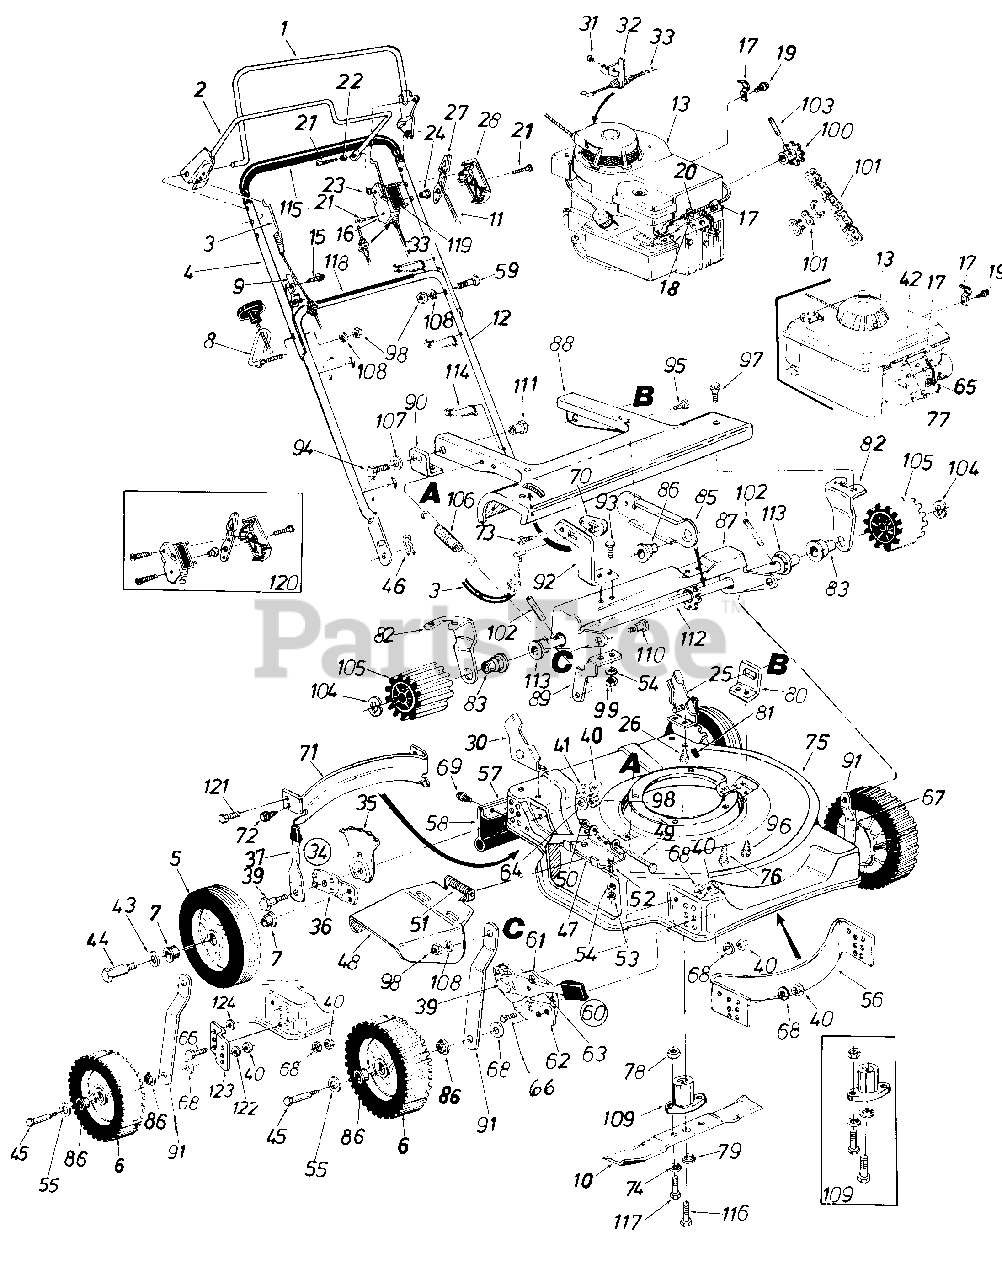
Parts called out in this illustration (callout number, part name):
1	Control Handle Ass'y.
2	Control Handle
3	Control Cable w/Spring- 47" Lg. (Green)
4	Upper Handle
5	Rear Wheel Ass'y. Comp.
6	Front Wheel Ass'y. Comp.
7	Flange Brg. 1/2" I.D.
8	Rope Guide Bolt
9	Cable Mtg. Brkt.
10	22" Blade
11	Throttle Wire-58" Lg. (Green)
12	Lower Handle
13	Engine
15	Hex AB-Tap Scr. 5/16-18 x 314
16	Clutch Panel Half
17	Casing Clamp
18	Hex AB-Tap Scr. #8 x .50 Lg.
19	Hex B-Tap Scr. #10 x .38 Lg.
20	Casing Clamp
21	Truss Hd. B-Tap Scr. #12 x 1.5" Lg.
22	Spacer .23 I.D. x .30 O.D.
23	Spr. Wash. .206 I.D. x .448 O.D.
24	Control Disc Pin
25	Handle Mtg. Brkt. Ass'y.
26	Hex B-Tap Scr. 5/16-18 x .50"
27	Throttle Control Lever
28	Control Panel Half
30	Handle Mtg. Brkt. Ass'y.
31	Pop Rivet .156 Dia. x .316 Lg.
32	Cable Bracket
33	Control Cable-43" Lg. (Yellow)
34	Rear Height Adjustment Ass'y.-R.H.
35	Index Plate
36	Wheel Pivot Bar
37	Spring Lever w/Knob
39	Shld. Bolt .500" Dia. x .430" Lg.
40	Hex Nut 3/8-16 Thd.
41	Bell-Wash. .39 I.D. x 1.38 O.D. x .062
42	Casing Clamp
43	Bell-Wash. .40 I.D. x .88 O.D. x .06
44	Rear Axle Bolt
45	Front Axle Bolt
46	Int. Cot. Pin 5/16 Dia.
47	Adapter Plate
48	Chute Deflector Ass'y.
49	Pivot Pin
50	Cap Speed Nut 1/4 Rod
51	Torsion Spring
52	Hex Bolt 1/4-20 x .50 Lg.
53	Hex Nut 1/4-20 Thd.
54	L-Wash. 1/4" I.D.
55	Fl-Wash. .531 I.D. x .93 O.D. x .090
56	Front Baffle
57	Retaining Strip-14" Lg.
58	Rear Flap
59	Carr. Bolt-5/16-18 x 1.75" Lg.
60	Front Height Adjustment Ass'y.-R.H.
61	Index Plate
62	Pivot Bar
63	Spring Lever w/Knob
64	Bell-Wash. .345 I.D. x .88 O.D.
65	Spark Plug Insulator
66	Hex Bolt 3/8-16 x .75
67	Front Height Adjustment Ass'y.-L.H.
68	Bell-Wash. .400 I.D. x .88 O.D. x .060
69	Hex Tap Scr. 1/4 x .62 Lg.
70	Barrel Cable Hold Down-L.H.
71	Rear Baffle
72	Truss Mach. Scr. #10 x .50
73	Hex B-Tap Scr. #10 x .44" Lg.
74	L-Wash. 5/16" I.D.
75	22" Deck Ass'y
76	Hex TT-Tap Scr. 3/8-16 x 1.0" Lg.
77	Hex "B"-Tap Scr. #10 x .62" Lg.
78	Hex Nut 5/16-24
79	L-Wash. 3/8" I.D.-H.D.
80	Pivot Bracket
82	Axle Bracket
83	Fl. Ball Brg. 1/2" I.D.
85	Brg. Support
86	Fl. Ball Brg. 1/2" I.D.
87	Drive Engagement Cam
88	Front Pinion-Pivot Cover
89	Spring Mtg. Brkt.
90	Pivot Bracket
91	Link-5.30 x .88"
92	Engage. Arm-R.H.
93	Carr. Bolt 1/4-20 x .62 Lg.
94	Hex Bolt 3/8-16 x .50 Lg.
95	Hex B-Tap Scr. 1/4 x .38 Lg.
96	Hex AB-Tap Scr. 1/4 x .62 Lg.
97	Hex AB-Tap Scr. 1/4 x .62 Lg.
98	Hex Nut 5/16-18 Thd.*
99	Hex Nut 1/4-20 Thd.
100	10 Tooth Sprocket Ass'y.
101	#48 Chain 1/2" Pitch- 50 Links
102	Spring Pin 3/16 Dia. x 1.25 Lg.
103	Spring Pin 3/16 Dia. x 1.00 Lg.
104	E-Ring
105	33 Tooth Drive Pinion
106	Ext. Spring-.50 O.D. x 4.25 Lg.
107	Bell-Wash. .400 I.D. x .88 O.D. x .060
108	L-Wash. 5/16" I.D.
109	Blade Adapter Kit
110	Shld. Bolt .437 Dia. x .162 Lg.
111	Shld. Nut .625 Dia. x .165 Lg.
112	Pinion Shaft w/7 Tooth Sprocket
113	Fl. Ball Bearing 1/3" I.D.
114	Cable Tie
116	Hex Bolt 3/8-24 x 2.25" Lg.
117	Hex Bolt 5/16-24 x 1.0" Lg.
118	Instruction Label
119	Control Label
120	Kit-Control Housing Comp.
121	Hex Bolt 5/16-18 x .75" Lg.
122	L-Wash. 3/8" I.D.
123	Wheel Brkt.
124	Fl-Wash. .385" I.D. x .62" O.D.
